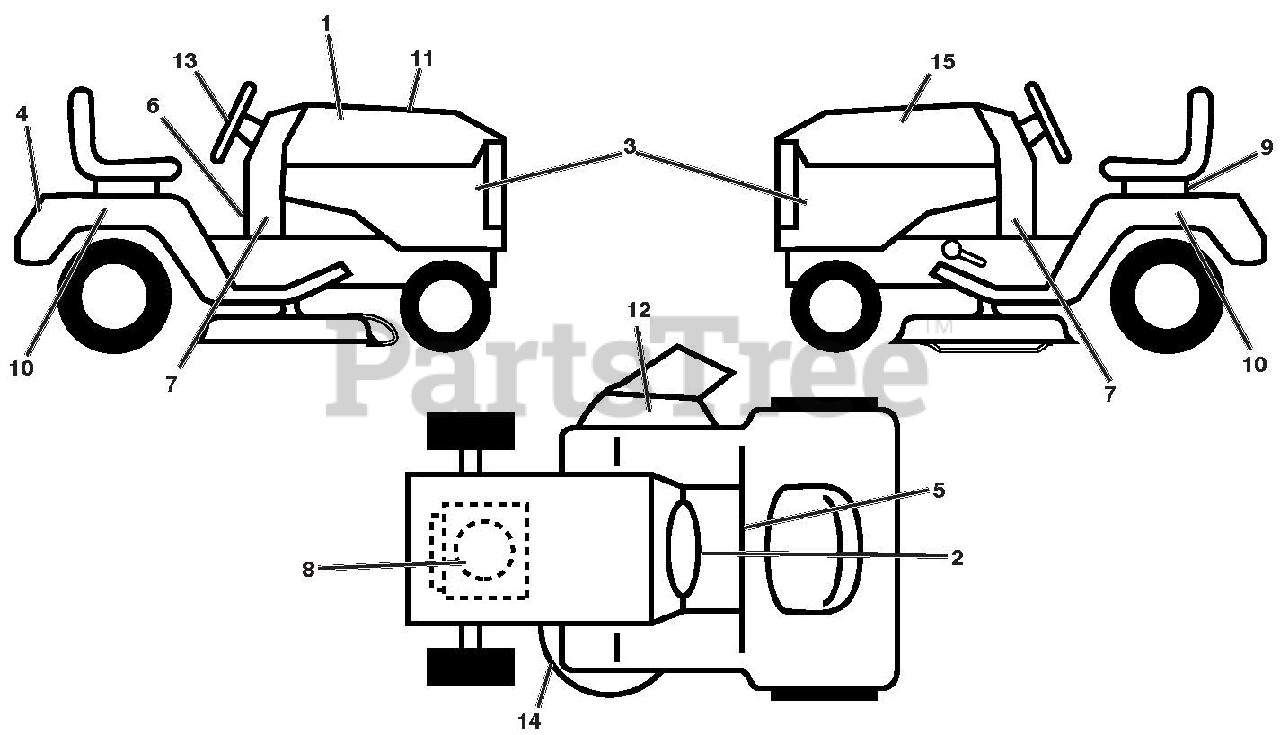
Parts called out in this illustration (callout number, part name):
1	DECAL.HOOD.RH
2	DECAL.WARNING.START
3	DECAL.SDPNL.PWRDBY B&S.ARIENS
4	DECAL.FENDER.REAR.ARIENS
5	DECAL.FENDER
6	Decal, Spark Arrester
7	DECAL, DASH LOWER
9	DECAL.BAT.DAN/POI P/L SYM.WPN
10	DECAL, FENDER
11	DECAL.REPLACEMENT
12	DECAL DECK/DEFLECT. WARNING
13	DECAL.WHEEL.STEER.ARIENS
14	DECAL.V-BELT.SCH.
15	DECAL.HOOD.LH
